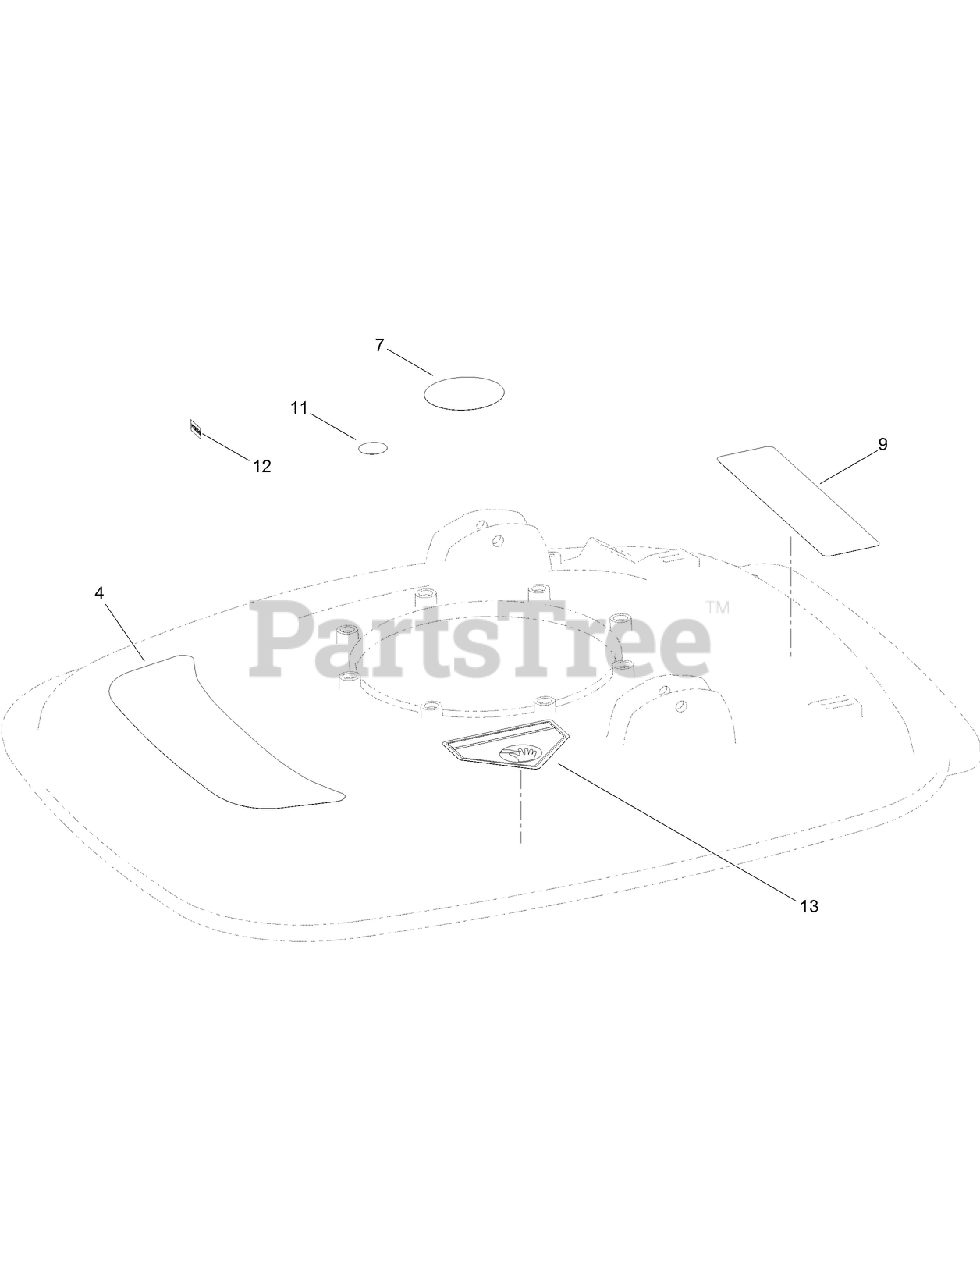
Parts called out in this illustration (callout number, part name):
4	DECAL-HOVER PRO
7	DECAL-ENGINE
9	DECAL-WARNING
11	DECAL
12	DECAL-STOP
13	DECAL-DANGER
